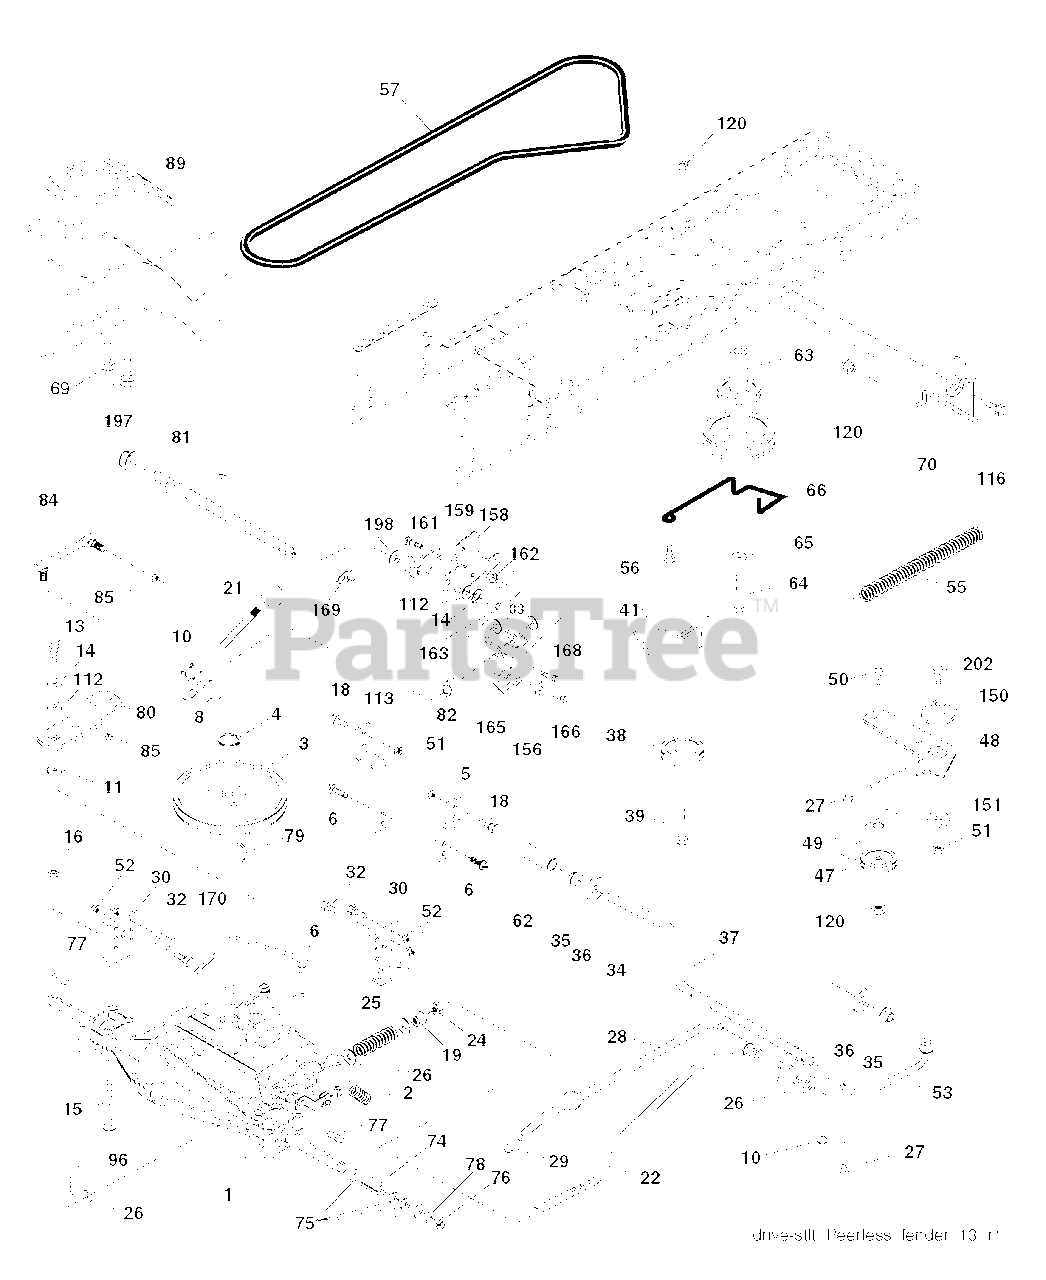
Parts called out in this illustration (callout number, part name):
2	SPRING,BRAKE RETURN
3	PULLEY TRANS
4	RETAINING RING LT
5	STRAP TORQUE
6	SCREW 5/16"
8	ROD SHIFT FENDER ADJUST LT
10	PIN COTTER
11	WASH-SHFT PLT LT
13	Bolt, 1/4-20 unf Grade 8 w/Patch
14	LOCKWASHER
16	NUT.71038.31-18.HEX.NYLOCK
19	NUT
21	KNOB T (1/2-HOLE)
22	ROD BRAKE
24	NUT
25	SPRING ROD LT
27	COTTER PIN
28	ROD, PARKING BRAKE
29	PLUNGER CAP
32	BOLT
34	SHAFT, FOOT PEDAL
35	BEARING.NYLON
36	WASHER LT
38	PULLEY IDLER COMPOSITE
41	KEEPER, BELT IDLER
47	Idler Pulley
48	BELLCRANK, CLUTCH
49	RETAIN BELT
50	BOLT.3/8-16X1.50
51	LOCKNUT
52	LOCKNUT
53	LINK.CLUTCH.7.66.2005
55	SPRING, RETURN LT
56	SCREW.3/8-16
57	BELT, V GROUND DRIVE 95 25
63	ENGINE PULLEY
64	BOLT HEX 7/16-20X4-1/4"
65	LOCKWASHER
66	KEEPER BELT ENGINE
69	SCREW.HI-LO.CONSOLE
70	KEEPER BELT ENG
74	SPACER AXLE
76	E-RING LT
77	SQUARE KEY
79	KEY STD (1373) DANA
80	ARM SHIFT
81	SHAFT ASM CROSS TAPERED
82	SHIFT SPRING
83	WASHER
84	LINK.TRNSAXLE
85	NUT LOCK CENTER 1/4 -28 FNTHD
89	CONSOLE SHIFT STLT
112	WASHER LT
113	STRAP TORQUE LH LT
120	NUT LOCK FLG 3/8-16 UNC
150	SPACER, RETAINER
151	WASHER 12/32X2X10GA
156	WASHER.SRRTD.5/16
158	BRACKET.SHIFT.MOUNT
159	HUB.SHIFT
161	BOLT
162	NUT.CROWNLOCK.1/4
165	BRACKET.PIVOT.LEVER
168	BOLT.SHOULDER.5/16-18X
169	PLATE.FASTENING.CROSS.SHAFT
170	KEEPER BELT T/A
197	NYLINER SNAP 5/8" ID
198	WASHER.NYL.7/8IDX.105"HYD CR
202	BOLT
